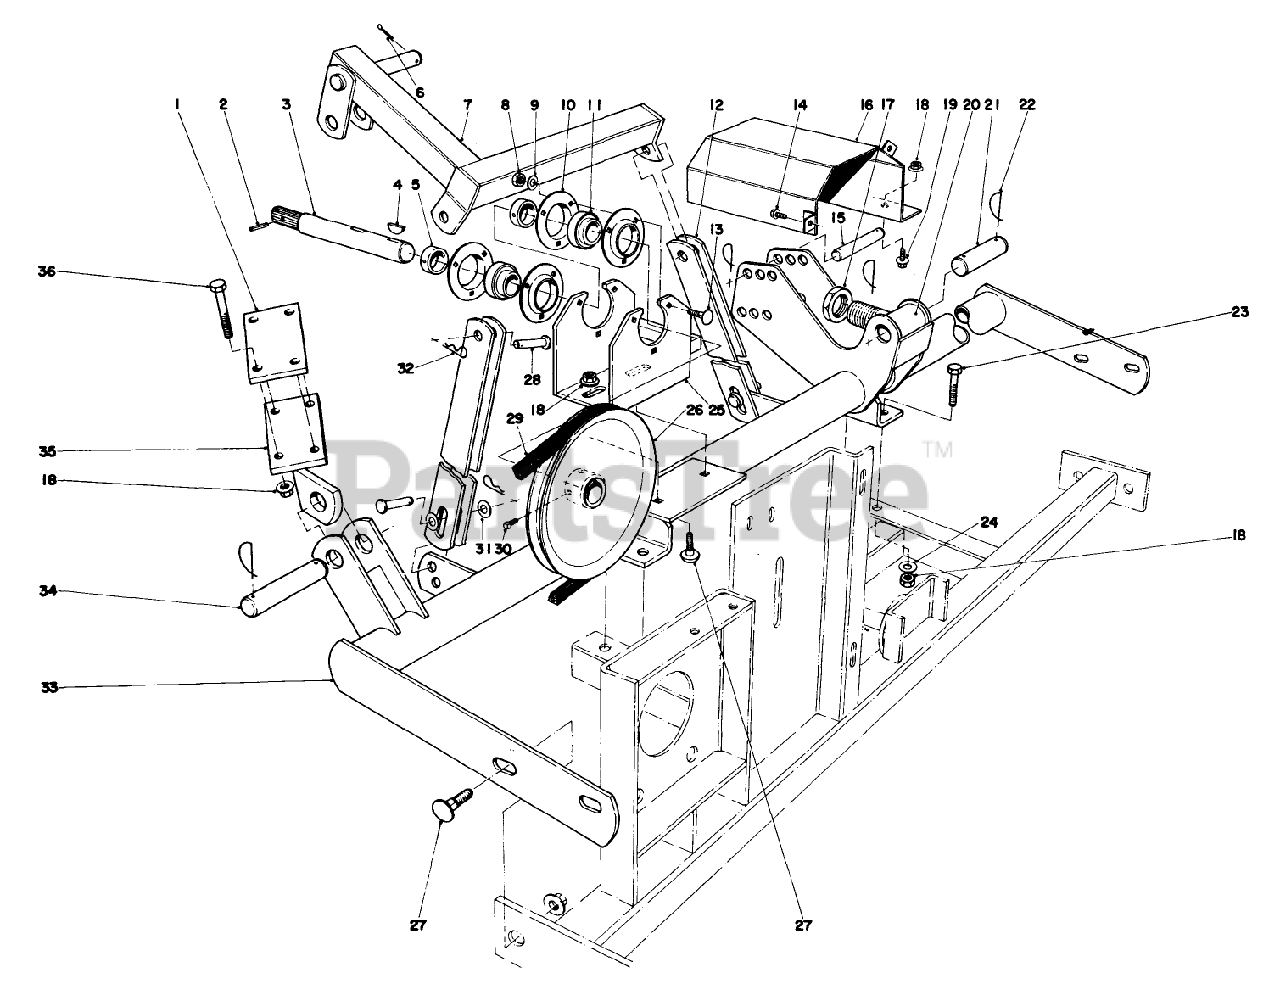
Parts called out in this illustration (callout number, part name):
1	Camp Plate
2	PIN-ROLL, SLOTTED
3	JACKSHAFT
4	KEY-WOODRUFF
5	Collar
6	PIN-COTTER
7	LIFT ARM WA
8	NUT-HEX
9	WASHER-LOCK/SP
10	FLANGE
11	Bearing (Incl. Ref. #5)
12	LIFT STRAP
13	BOLT-CARR
14	SCREW-HHF
16	Power Take Off Shield
17	NUT-HJ
18	NUT-HHF, WHIZ
19	SCREW-HHF
20	Push Pin
21	PIN-PLAIN
22	PIN-LYNCH
23	SCREW-HH
24	WASHER-FLAT
25	JACKSHAFT SUPPORT
26	PULLEY 9 IN OD
27	BOLT-CARR
28	PIN-CLEVIS
29	V BELT
30	SCREW-SQH
31	WASHER-FLAT
32	PIN-COTTER, HAIR
33	Hitch Adapter
34	Pin
35	Push Arm Bracket
36	SCREW-HH
